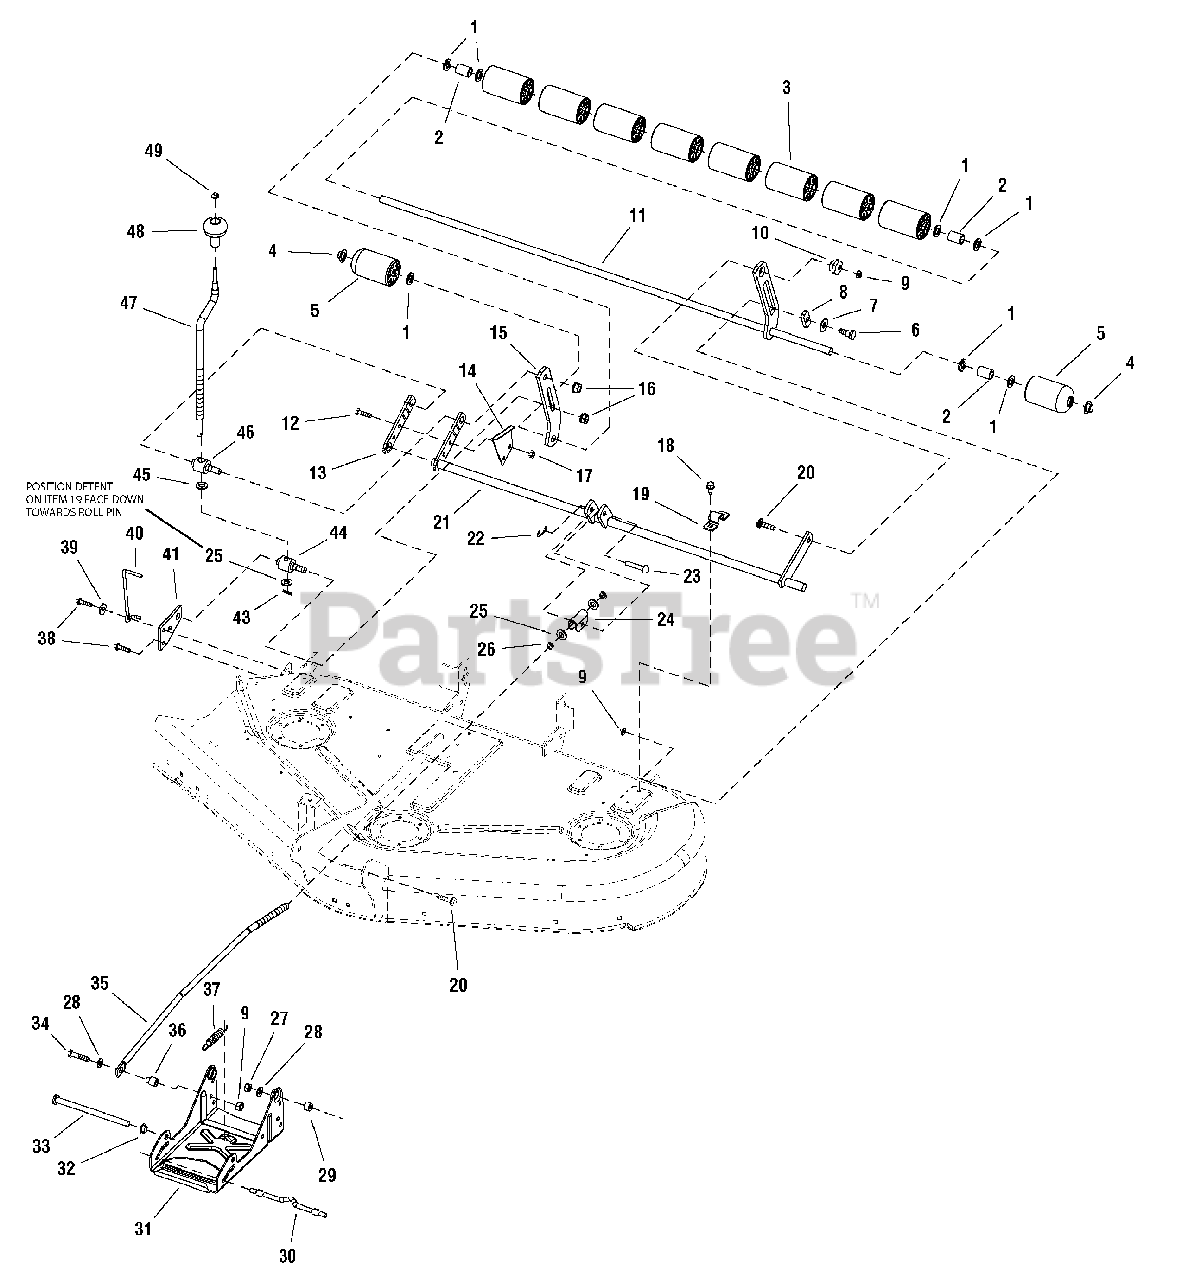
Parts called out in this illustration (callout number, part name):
1	WASHER, 5/8
2	SPACER, 1-1/4 x 5/8
3	ROLLER
4	PUSH NUT, 5/8
5	ROLLER, Rounded End
6	SHOULDER BOLT
7	WASHER, Plain
8	SLIDE
9	NUT, Hex Toplock Spiral Flange, 3/8-16
10	NUT, Adjuster
11	ROCKER SHAFT ASSEMBLY, 50"
12	CAPSCREW, Hex Head, 5/16-18 x 1-1/4
13	ARM, Rear
14	BRACKET, Cutting Height
15	BAR, Roller 44", 50"
16	NUT, Hex Head, 1/2-13
17	NUT, Hex, 5/16-18 NC-2B
18	CAPSCREW, Hex Head, Taptite, 5/16-18 x 3/4
19	STRAP
20	CARRIAGE BOLT, 3/8-16 x 1-1/2
21	SHAFT ASSEMBLY, Rocker 50"
22	CLIP, Spring
23	Pin
24	TRUNNION
25	WASHER, 1/2
26	LOCKNUT, Hex, Jam, 1/2-13
27	NUT, Hex ESNA Lock, 3/8-16
28	WASHER, 3/8
29	SPACER
30	ROD
31	SUPPORT, Mower
32	NUT, Push, 1/2
33	ROD
34	CAPSCREW, Hex Head, 3/8-16 x 1 3/4
35	ROD, E-Coat, 1/2-13 x 5.3, 28.900LG
36	SPACER, 3/8 x 3/4 x 15/16
37	SPRING, Extension
38	CAPSCREW, Taptite, 5/16-18 x 1-1/4
39	WASHER, Plain, 5/16
40	ROD, Indicator, Cutting Height
41	PLATE, Mower Support
43	PIN, Spring
44	TRUNNION
45	WASHER, Detent
46	TRUNNION, Threaded
47	CRANK, Height Adjustment, Black
48	KNOB, Chute Control Spinner
49	NUT, Push, 3/8
